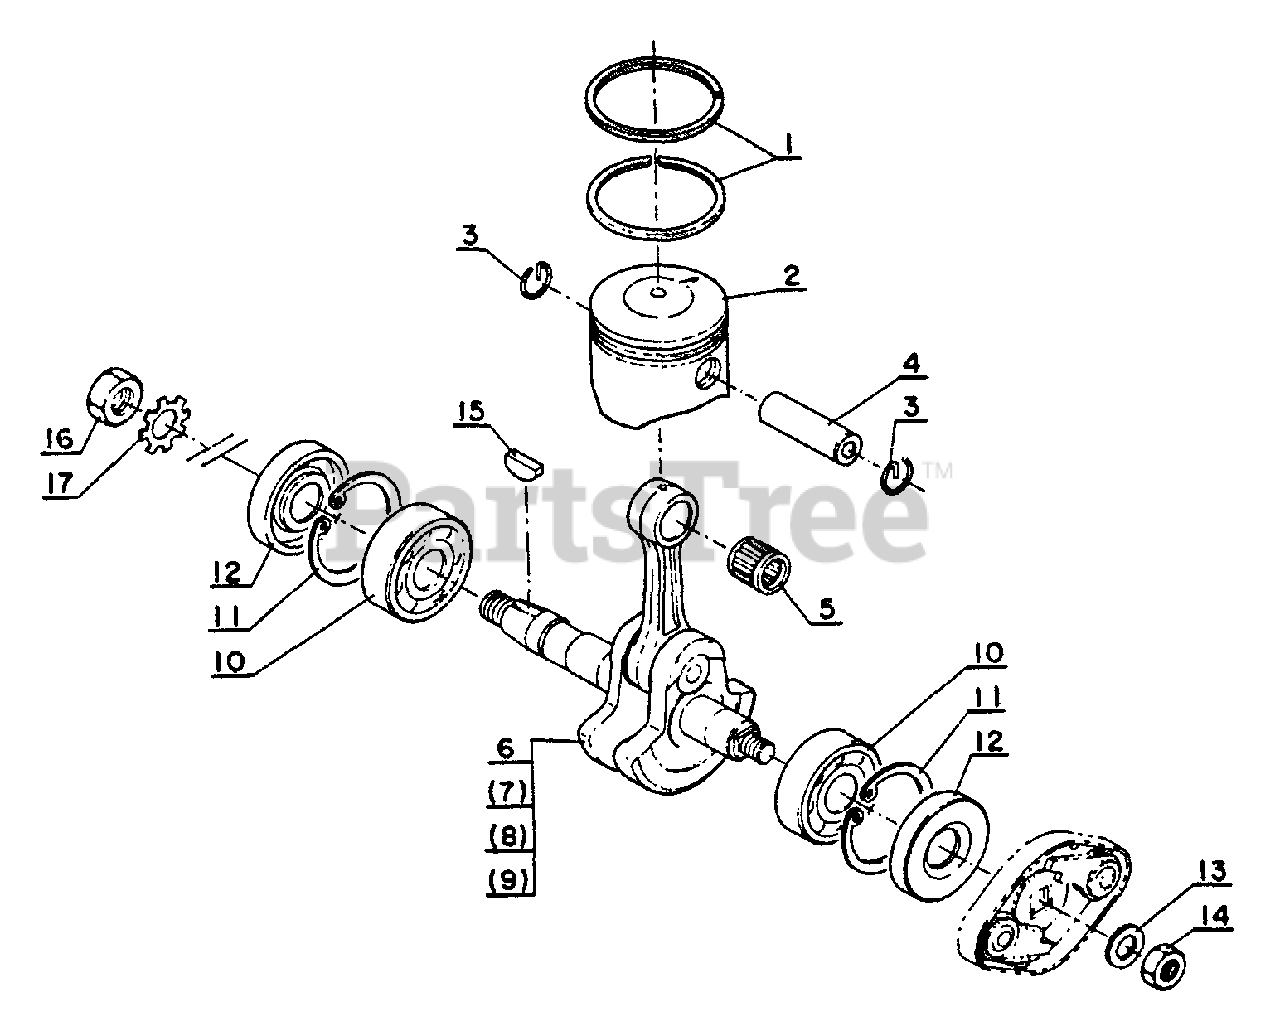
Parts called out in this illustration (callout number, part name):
1	RING, PISTON
2	PISTON
3	RING, RETAINING
4	PIN, PISTON
5	BEARING, NEEDLE
6	CRANKSHAFT ASSY
10	BEARING, BALL - 6201 C3
11	RING, SNAP Ø32
12	SEAL, OIL 12
13	WASHER 6.5×11.5×0.8
14	LOCKNUT - 6
17	LOCKWASHER - 8
